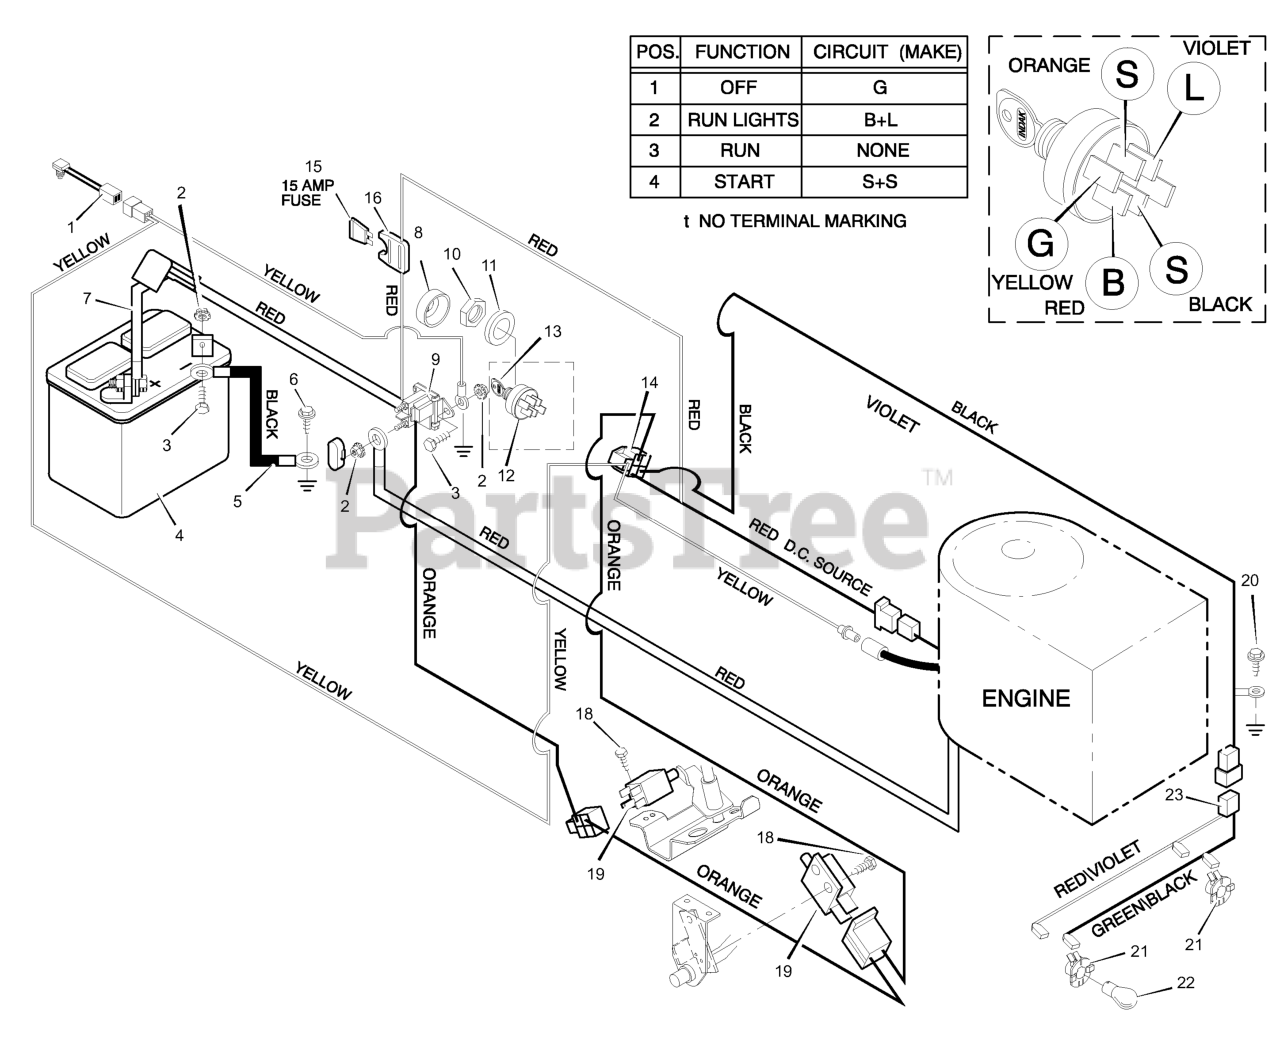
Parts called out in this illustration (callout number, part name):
1	Switch, Seat Sensor
2	Locknut
3	Bolt, Hex
4	Battery
5	Cable, Battery Ground
7	Cable, Red Battery
8	Cap, Ignition
9	Solenoid
10	Nut
12	Switch, Ignition
13	Key, Ignition
14	Harness, Chassis Wire
16	Holder, Fuse
19	Switch, Clutch
20	Screw
21	Socket, Light
22	Bulb, Light
23	Harness, Light Wire
24	Cover, Terminal
